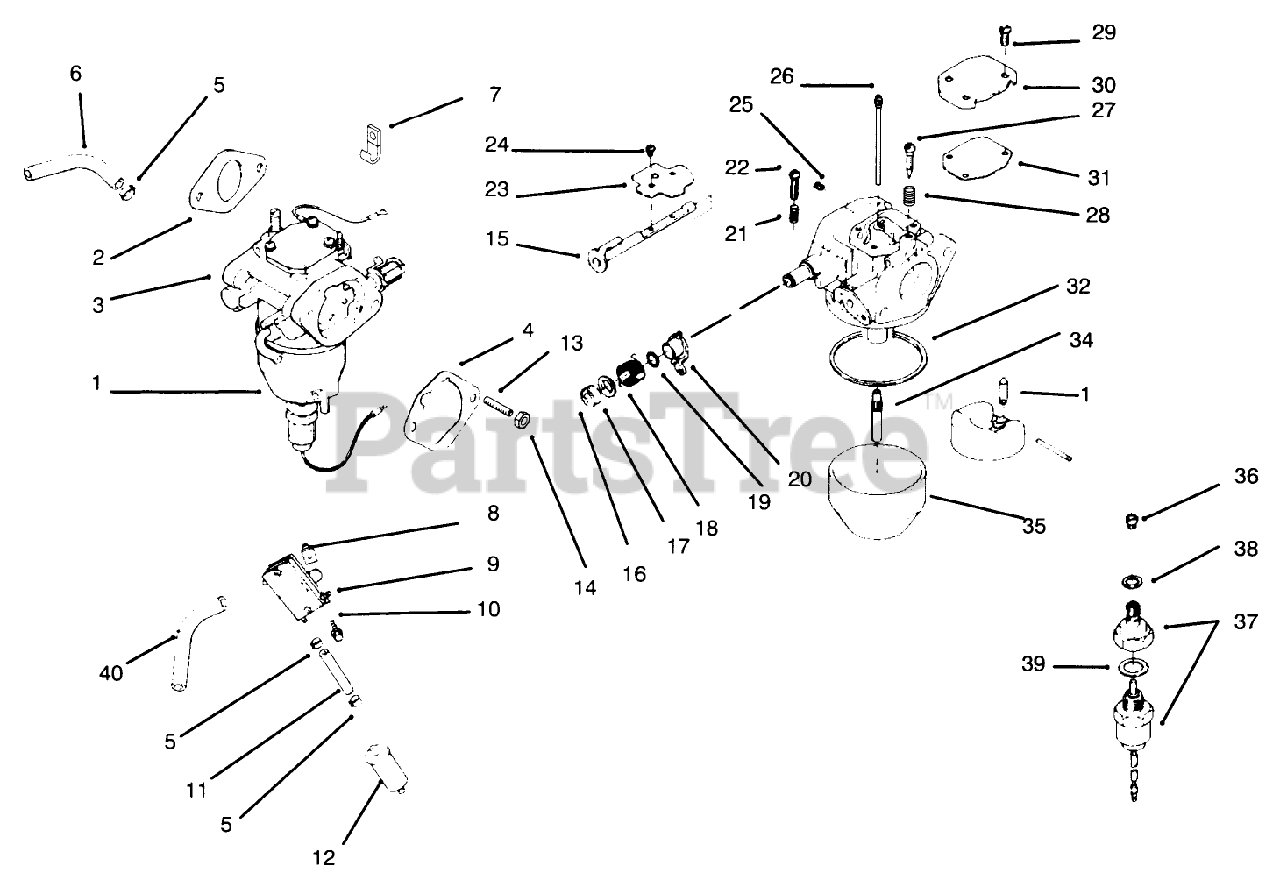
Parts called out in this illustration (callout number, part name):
1	Kit Carburetor /w Gasket (Incl. Ref. #2-4)
2	Kit-Carburetor
3	Carburetor (Ref.Only) (Inc. Ref. 15-39)
4	Gasket-A/C Base
5	Clamp
6	Line-Fuel 12"
7	Clamp
8	Nut
9	Pump-Fuel
10	Screw
11	Line-Fuel
12	Filter-Fuel
13	Stud
14	Nut
15	Shaft-Choke
16	Washer
17	Collar-Coke
18	Spring-Choke Return
19	Ring-Choke Lever
20	Lever-Choke
21	Sprin-Throttle Screw
22	Screw-Throttle Adjust
23	Plate-Choke
24	Screw
25	Jet-Air Bleed
26	Jet-Slow
27	Screw
28	Spring-idler Screw
29	Screw
30	Cover-Passage
31	Gasket-PassageCover
32	Gasket-FloatChamber
34	Nozzle-Main
35	Chamber-Float
36	Jet-Main
37	Kit-Solenoid Valve (Incl. Ref. #38-39)
38	Gasket-ChamberScrew
39	Gasket-Solenoid
40	Line, fuel
